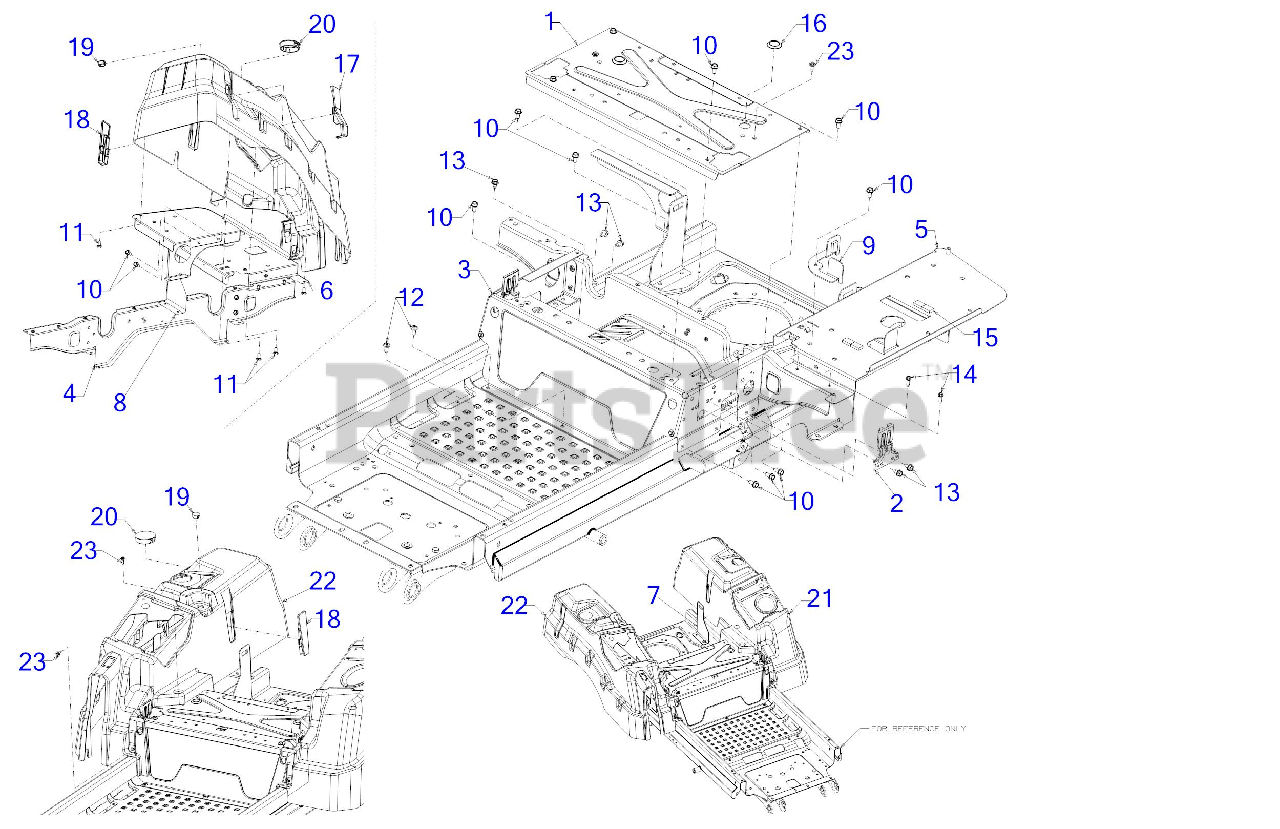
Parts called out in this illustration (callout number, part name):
10	SCREW 5/16-18 x .750
11	SCREW 5/16-14 x .750
12	SCREW 5/16-18 x .750
13	SCREW 5/16-18 x .500
14	SCREW 1/4-20 x .750
15	FOAM TAPE .625 WIDE x .25 THK BULK
17	CONSOLE PLUG (RH) OUTER
18	CONSOLE PLUG (RH) INNER
19	CONSOLE PLUG (RH)
20	FUEL NECK PLUG
21	CONSOLE (LH) 2.25" CAP
22	CONSOLE (RH) 2.25" CAP
23	SHOULDER SCREW M6-1 .368 X.115
